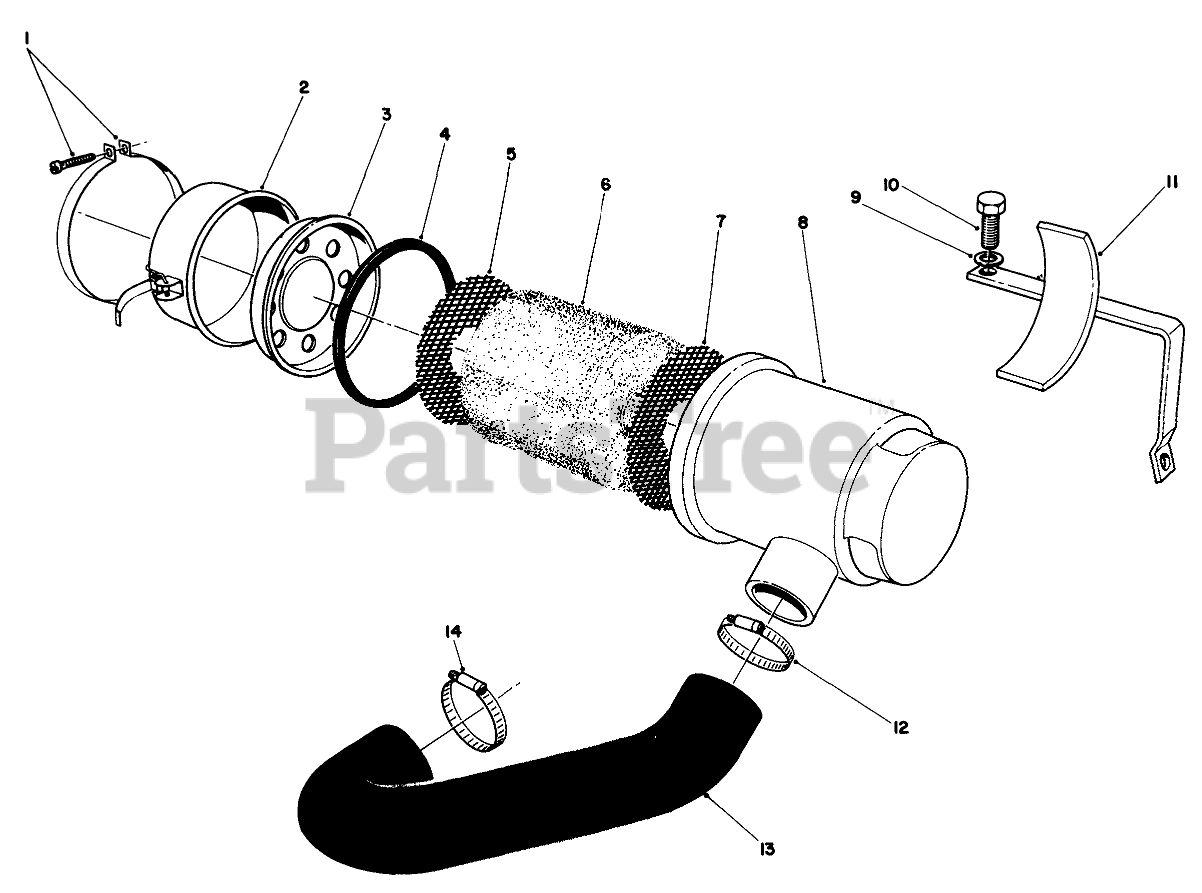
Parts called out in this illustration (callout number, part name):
1	Tension Clamp
2	OIL PAN
4	Gasket
5	SCREEN
6	Cartridge-Filter
7	SCREEN
8	Oil Bath Air Cleaner Assembly (Incl. Ref. #2-7)
9	Lockwasher
10	Screw-Hex Head
11	Support
12	Clamp-Tension
14	Clamp-Tension
